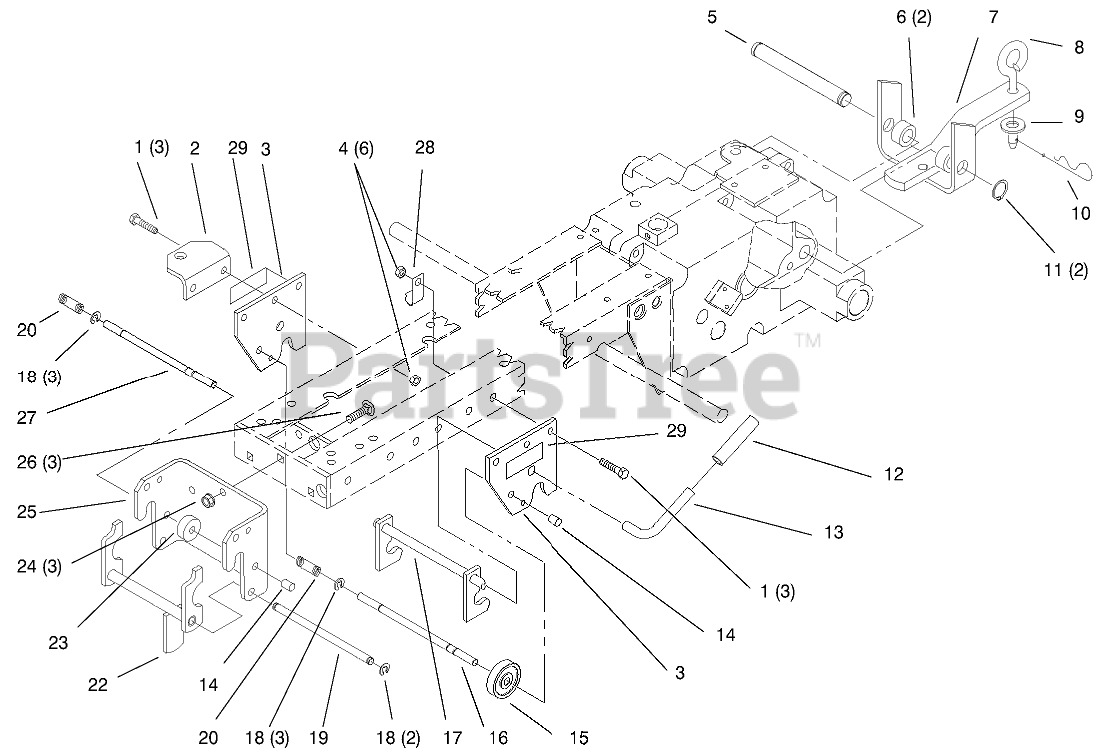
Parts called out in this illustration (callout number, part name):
1	SCREW-HH
2	Axle
3	Hitch Plate
4	NUT-LOCK, NI
5	PIN-STATIONARY HITCH
6	SPACER
7	Hitch
8	PIN-TOOL
9	WASHER-FLAT
10	PIN-HAIR
11	E-RING
12	GRIP
14	CAP-ROD, PLUNGER
16	ROD-LOCK
17	MID HITCH ASM
18	RING-RETAINING
19	ROD-LATCH PIVOT
20	SPRING
22	LATCH
24	NUT-LOCK, NI
25	Front Hitch
26	BOLT-CARR
27	ROD-LOCK
28	CLIP
29	DECAL - ATTACH-A-MATIC
